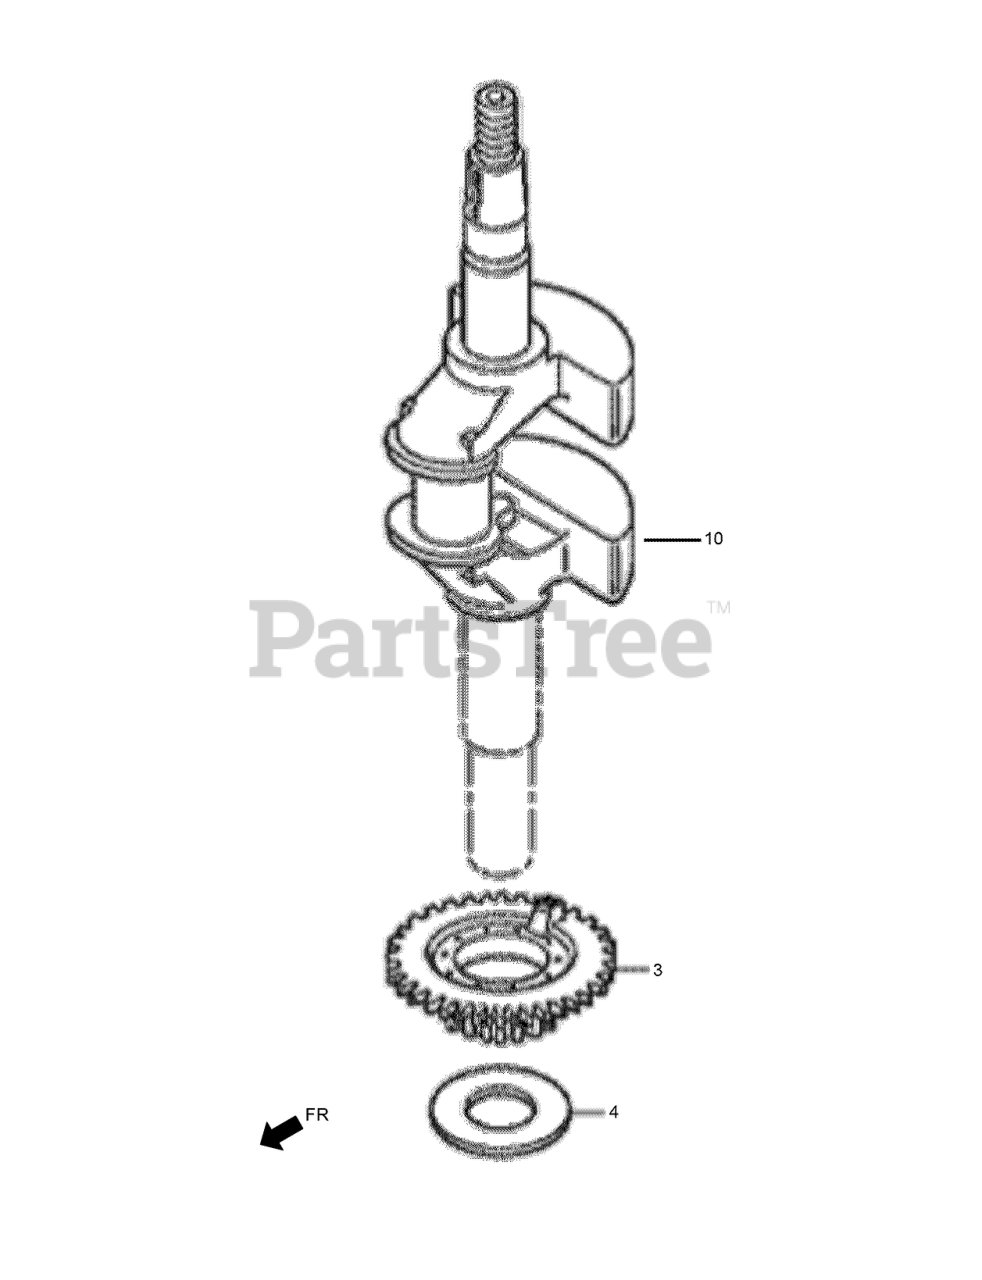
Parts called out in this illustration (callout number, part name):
3	PULLEY-TIMING BELT DRIVE
4	WASHER-THRUST
10	CRANKSHAFT
